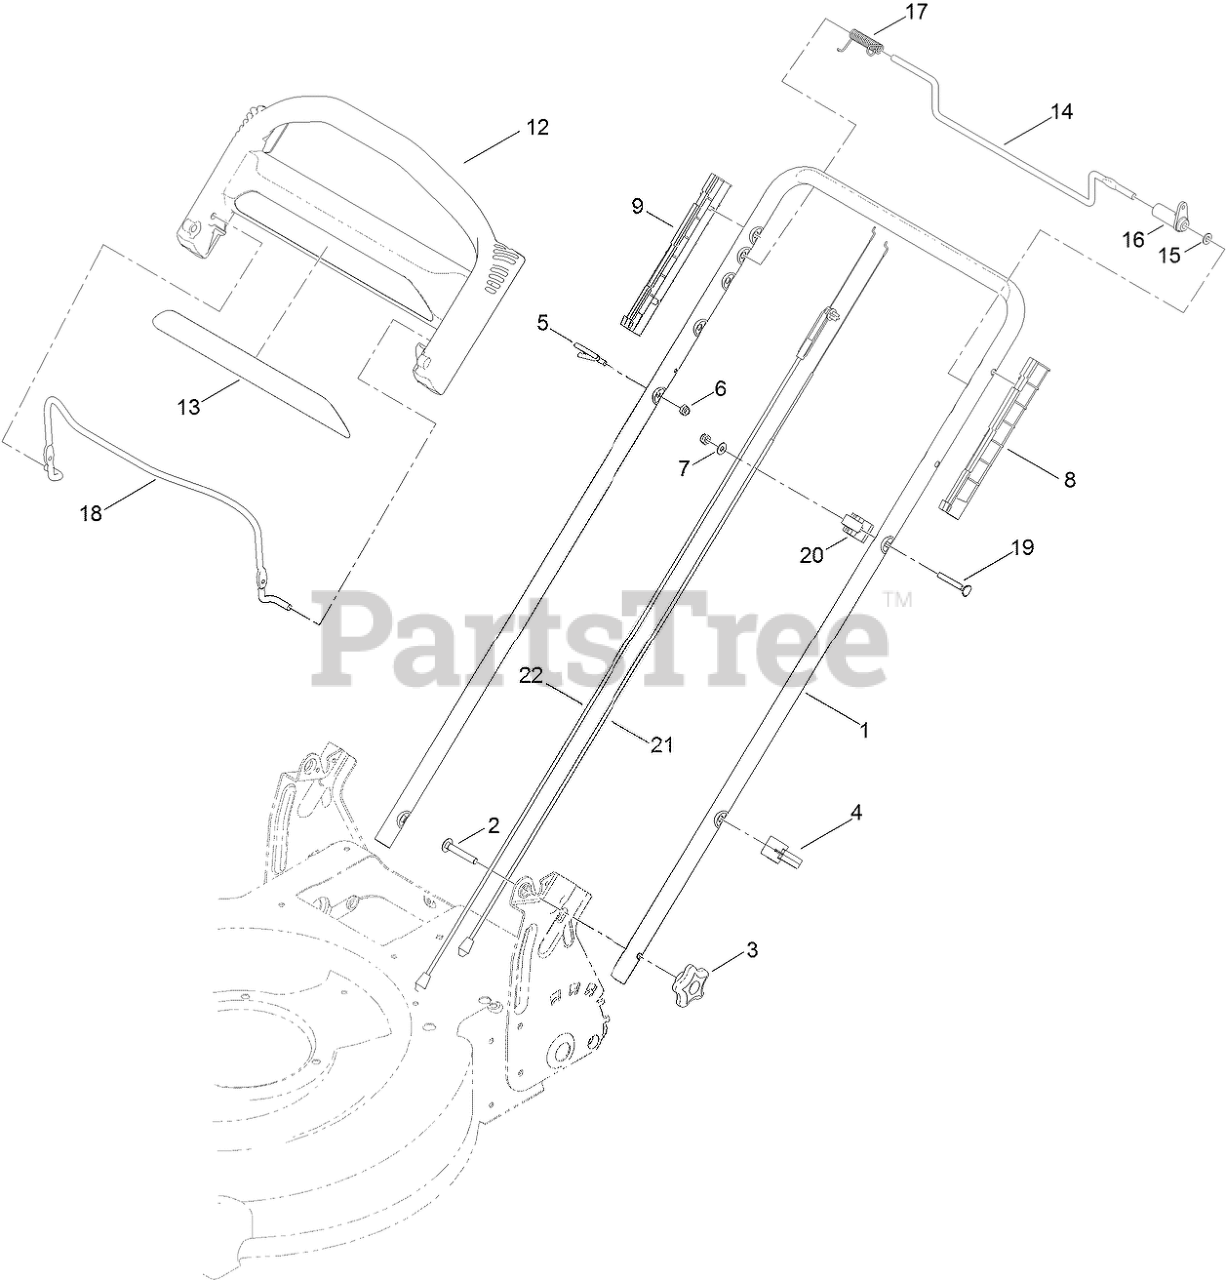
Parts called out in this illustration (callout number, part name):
2	Screw-CARR
3	KNOB-HANDLE
4	GUIDE-CABLE
5	GUIDE-ROPE
6	NUT-LOCK, NI
7	WASHER-FLAT
8	GUIDE-LH
9	GUIDE-RH
12	HANDLE-CONTROL
14	BAR-CONTROL, TRACTION
15	WASHER-PLAIN
16	LEVER-TRACTION
17	Spring-Torsion
18	Bail-Brake
19	SCREW
20	ANCHOR-CABLE
21	CABLE-TRACTION
22	CABLE-BRAKE
